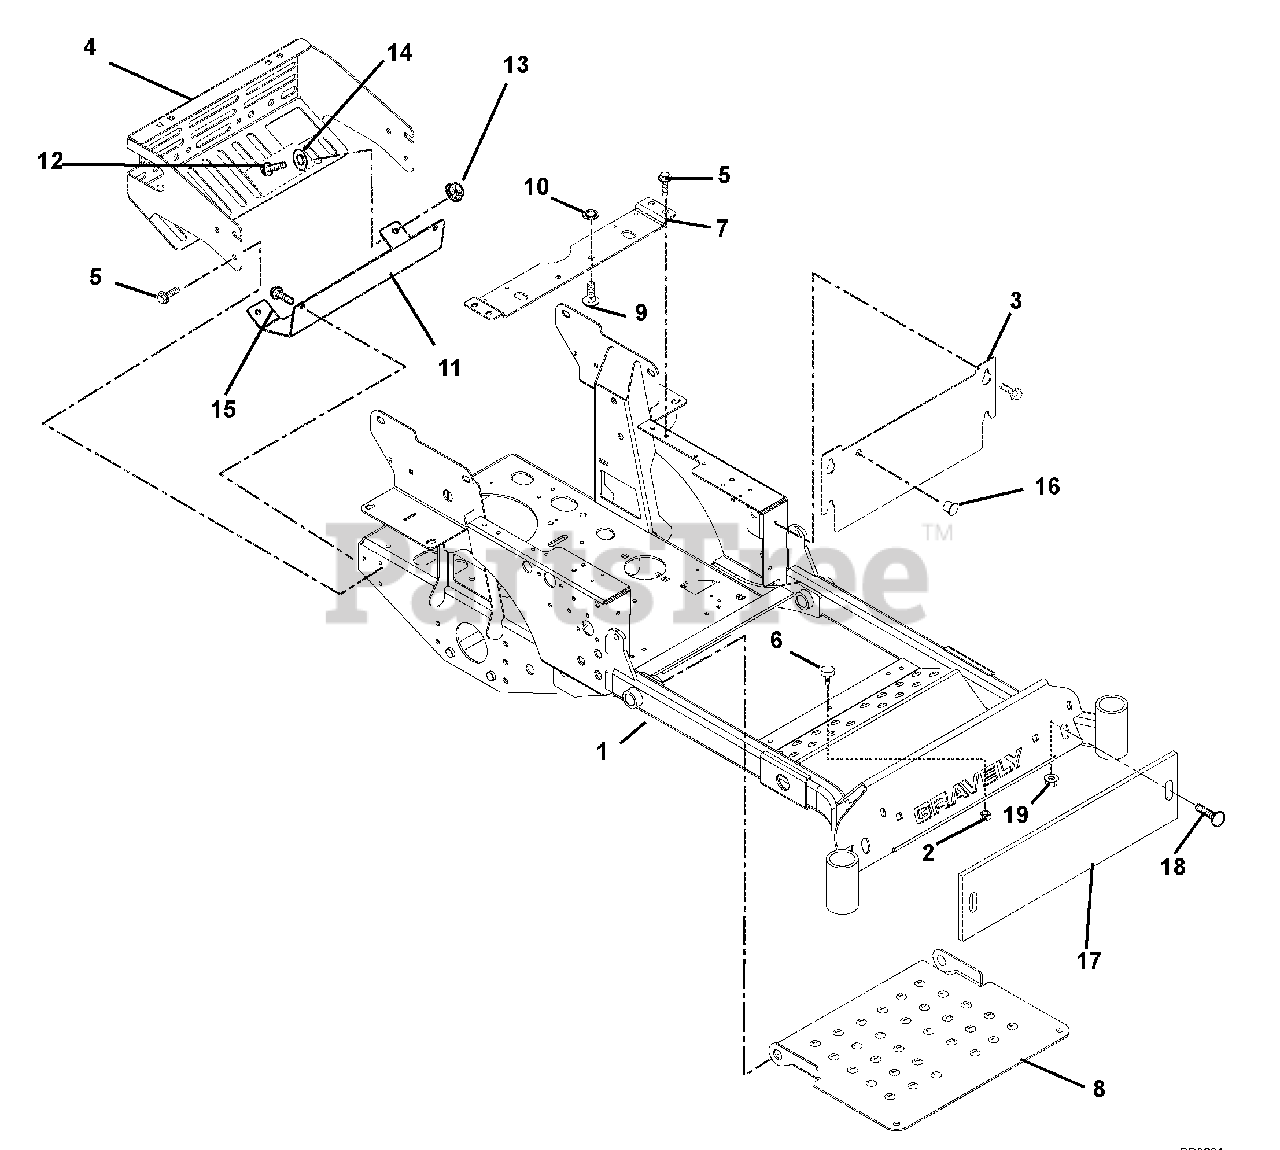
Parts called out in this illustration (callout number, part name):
1	Frame, Compact-Z (SN 000101 to 002499)
2	Nut, Spin Lock Flange .312-18
3	Access Panel
4	Bumper, Rear
5	Screw, Tapping .38-16 x .75 Hex Washer Head
6	Bumper, Rubber
7	Seat Support
8	Panel, Inspection
9	Bolt, Round Head Square Short Neck .31-18 x .75 Grade 5
10	Nut, Push .312
11	Heat Shield, Compact Z
12	Bolt, Hex .38-16 x .75 Grade 5
13	Nut, Nyloc Flange .38-16
14	Washer, Flat Steel .438 x 1.00 x .083
15	Screw, Tapping .38-16 x .50 Hex Washer Head
16	Plug, Hole .56
17	Counterweight CZ Front - Red (SN 002500 and up)
18	Bolt, Round Head Square Neck .50-13 x 2.50 Grade 5 (SN 002500 and up)
19	Nut .50-13 Nyloc Flange (SN 002500 and up)
